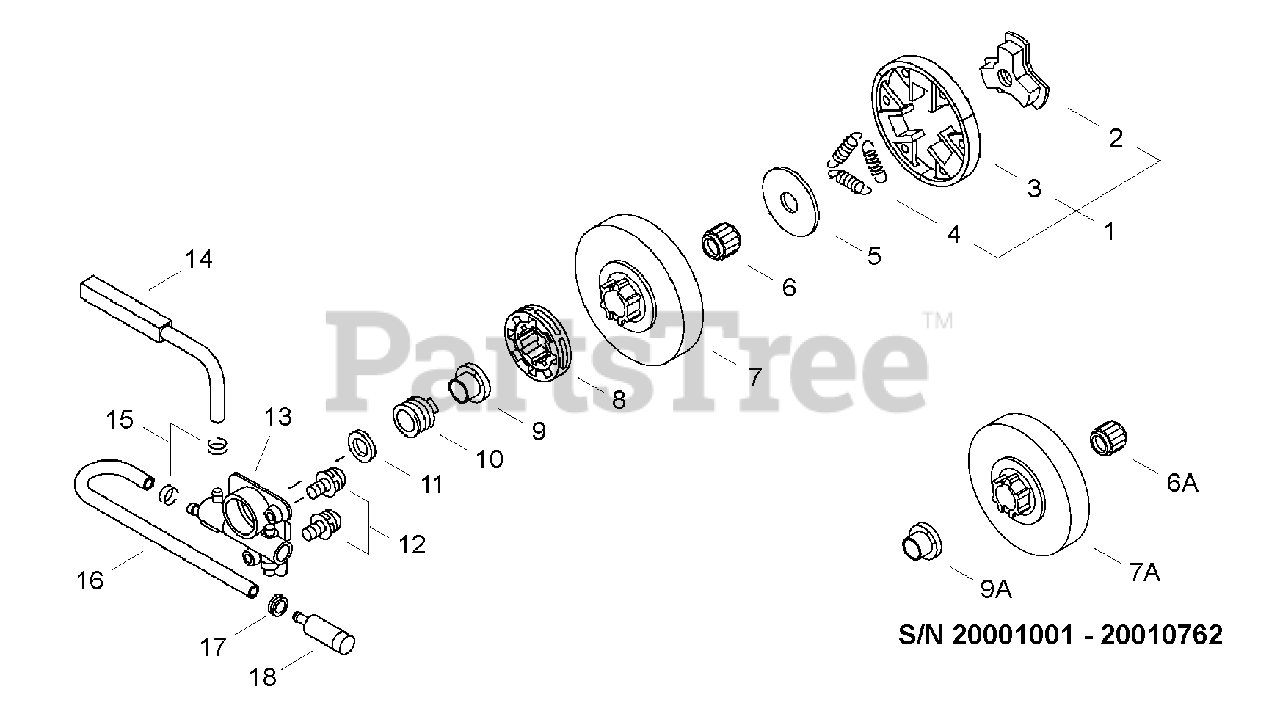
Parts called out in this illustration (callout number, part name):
1	CLUTCH ASSY
2	HUB, CLUTCH
3	CLUTCH SHOE SET
4	SPRING, CLUTCH
5	PLATE, CLUTCH
6	BEARING, NEEDLE
6A	BEARING, NEEDLE
7	DRUM, CLUTCH
7A	DRUM, CLUTCH
8	SPROCKET, RIM
9	COLLAR - 10
9A	COLLAR - 10
10	GEAR - WORM
11	WASHER - 11
12	SCREW - 4X12
13	AUTO-OILER ASSY
14	TUBE, OIL OUTLET
15	CLIP - 6.5
16	PIPE - OIL
18	FILTER, OIL
